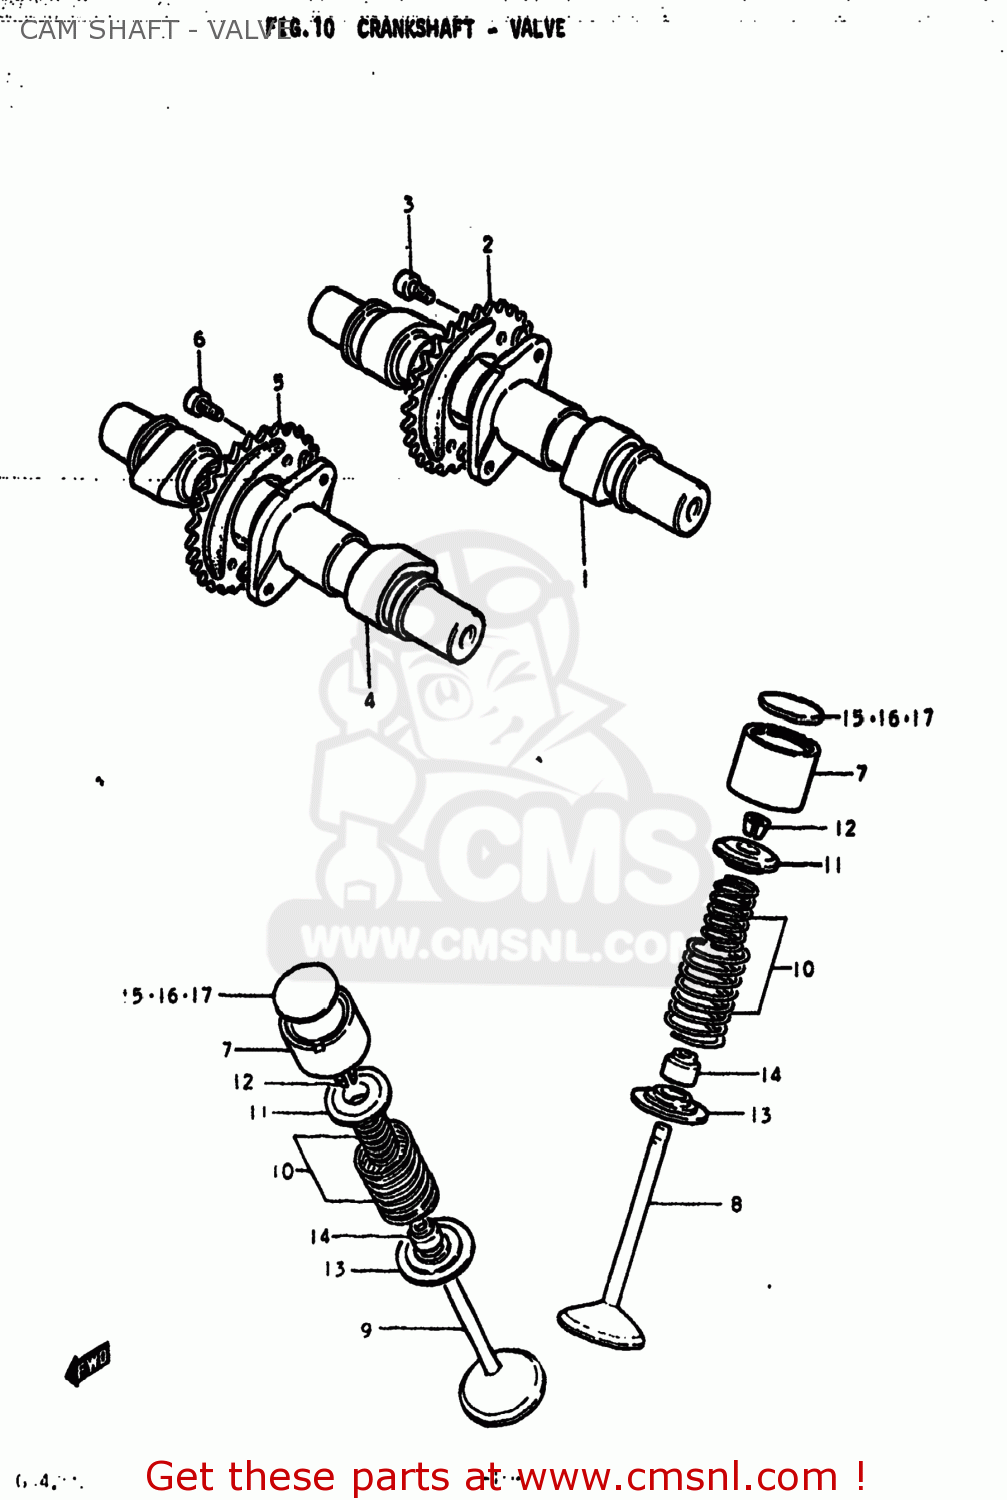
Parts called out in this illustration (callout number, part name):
1	CAMSHAFT
2	SPROCKET,CAMSHAFT
3	BOLT 6X11
4	CAMSHAFT,EXHAUST
5	SPROCKET,EXHAUST CAMSHAFT
6	BOLT 6X11
7	TAPPET
8	VALVE,INTAKE
9	VALVE,EXHAUST
10	SPRING SET,VALVE
11	RETAINER,VALVE SPRING
12	SHIM,TAPPET
13	SEAT,VALVE SPRING
14	SEAL,OIL(7X14.4X9)
15	SHIM,TAPPET
16	SHIM,TAPPET
17	SHIM,TAPPET
18	SHIM SET,TAPPET
19	CASE
